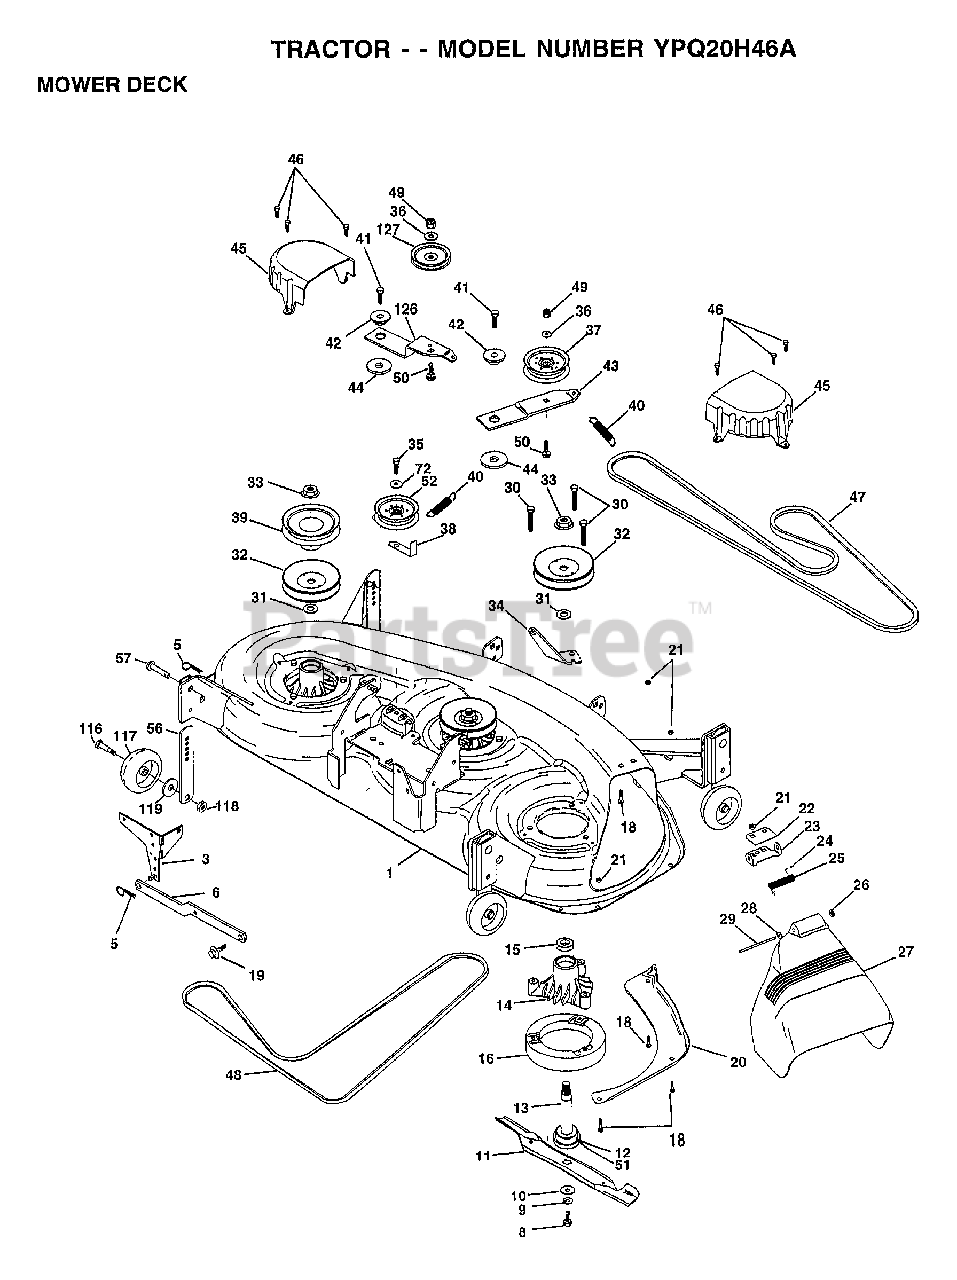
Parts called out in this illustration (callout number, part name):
1	DECK.WELDMENT.MOWER
3	BRKT.ASM.SW.44/50
8	BLADE BOLT
10	WASHER.HARD.BLADE
11	"BLADE MULCH 46"""
12	BEARING.BALL
13	SHAFT.ASM.W/BRNG
14	HOUSING.MAND.44.V
15	BEARING
16	STRIPPER RND MWR
18	BOLT
19	BOLT SHD 5/16-18
20	BAFFFLE.VORTEX.46
22	STIFFENER BRKT
23	DEFLECTOR BRKT
24	CAP-SLEEVE LT
26	NUT PUSH M
27	SHIELD DEFLECTOR
28	WASHER
29	HINGE ROD
30	"SCREW-THD ROLL,WA"
31	WASHER
32	PULLEY.MAND.36/46
34	ANCHOR.SPRING.46
35	SCREW LT
36	WASHER
37	FLAT IDLER PULLEY
38	"KEEPER BELT,IDLER"
39	PULLEY.DRV.DCK.46
40	"SPRING.SEC.44""VEN"
41	SCREW
42	SPACER.RETAINER.MOWER
43	ARM.IDLER.DECK.46
44	HARDENED WASHER
45	COVER.MANDREL.46
46	SCREW.1/4-20X5/8
47	BELT-V.SEC.46.KEL
48	BELT.MWR.PRM.85.4
50	BOLT.3/8-16X1.50
51	WASHER.FELT.
52	"PULLEY IDLER,FLAT"
57	RIVET-PAN HEAD
72	WASHER HYT
116	BOLT.SHOULDER
117	WHEEL GAGE DONUT
118	LOCKNUT
119	WASHER
126	ARM.IDLER.PRIM.46
127	PULLEY.IDLER.4.25
